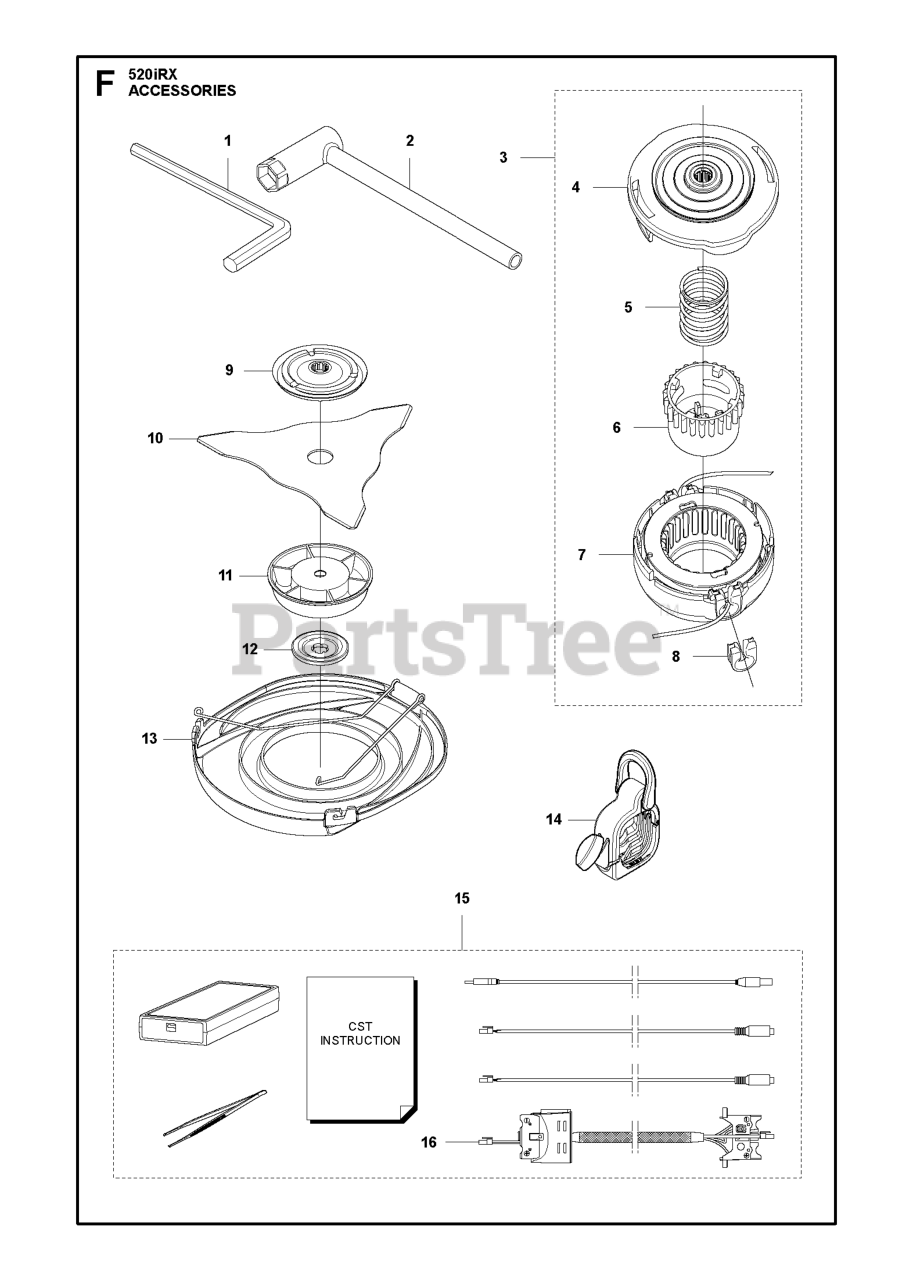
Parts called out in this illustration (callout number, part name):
2	COMBI WRENCH
3	TRIMMER HEAD T25B M10
4	HOUSING ASSY TRIMMERHEAD T25B
9	DRIVER ASSY
10	RP 10" MULTI BLADE 255-3T 1"
11	SUPPORTING CUP
12	SUPPORT FLANGE
13	BLADE GUARD TRANSPORT
15	DIAGNOSTIC TOOL KIT
16	WIRING ASSY
